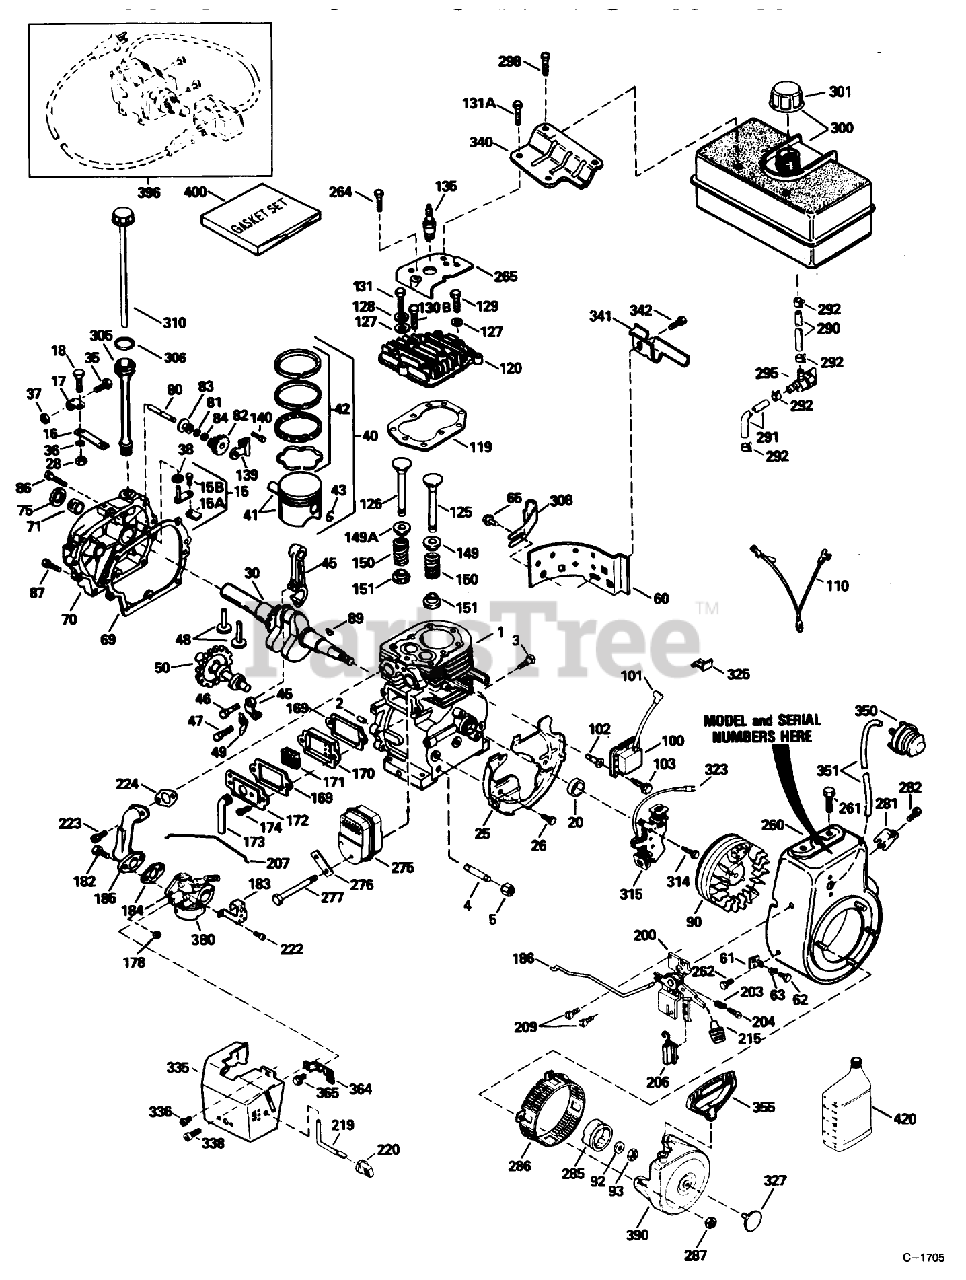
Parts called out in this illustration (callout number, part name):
1	Cylinder (Incl. ref. #2 20)
2	Pin-Dowel
3	Screw (1/4-20x1/2)
4	Nipple-Pipe
5	Cap-Pipe
15	Rod, Governor (Incl. Nos.62 63)
15A	Yoke-Governor
15B	Screw (6-40x5/16)
16	Lever-Governor
17	Clamp-Lever, Governor
18	Screw
18	Gasket-Carburetor To Intake Pipe
20	Seal-Oil
22	Gasket-Pipe, Intake
25	Baffle-Blower Housing
26	Screw (1/4-20x19/32)
28	Nut-Lock
30	Crankshaft
35	Screw
36	Washer-Lock
37	Nut-Lock
38	Ring-Retaining
40	Piston, Pin Ring Assy. Std.(Includes ref. #41, 42 43)
41	Piston Pin Assembly Standard (Includes ref. #43)
42	Ring Set (STD)
43	Retaining Ring-Piston Pin
45	Rod Assembly-Connecting (Incl. ref. #46, 47 49)
46	Bolt-Rod
47	Bolt-Rod
48	Lifter-Valve
49	Dipper-Oil
50	Camshaft (MCR)
60	Extension-Housing, Blower
61	Bracket
62	Screw (8-32 x 3/8)
63	Grommet
65	Screw
69	Cylinder Cover Gasket
70	Cover-Cylinder (Includes 71, 75, 80)
71	2025A77 WIZARD ROTA
75	Seal-Oil
80	Shaft-Governor
81	Washer-Flat
82	Gear Assy., Governor (Incl. Ref. #45)
83	Spool-Governor
84	Ring-Retaining
86	Screw (1/4-20x1-3/16)
87	Screw (1/4-20x1-11/16)
89	Key-Flywheel
90	Flywheel ASM
92	Washer-Belleville
93	Nut-Flywheel
100	Solid State ASM
101	Cover-Spark Plug
103	Screw
110	Ground Wire
120	Head-Cylinder
125	Valve, Exhaust (Standard)(Incl. No. 9)
126	Valve, Intake (Std.) (Incl. Ref. #58)
127	Washer-Flat
128	Washer-Belleville
129	Screw (5/16-18x1-25/32)
130	Screw
131	Screw (5/16-18 X 2)
131A	Screw
135	Spark Plug-Resistor (R J19 L M)
139	Bracket-Gear, Governor
140	Screw (10-24x1/2)
149	Cap-Spring, Valve
149A	51106 GILSON ROTARY
150	Spring-Valve
151	Keeper-Spring, Valve
170	Body-Breather
171	Element-Breather
172	Cover-Valve
173	Tube-Breather
174	Screw
178	Nut and Lock Washer (1/4-28)
182	Screw (1/4-28x1)
183	Bracket-Choke
185	Pipe-Intake
186	Link-Governor
200	Bracket-Control (Includes 19, 203, 204, 206)
203	Spring-Compression
204	Screw
206	Terminal
207	Link-Throttle
209	Screw (10-32 x 1/2)
215	Knob-Control
219	Rod-Choke
220	Knob-Control
222	Screw (10-32 x 1/2)
223	Screw (T-30, 5/16-18x1-3/32)
260	Housing-Blower
261	Screw (5/16-18x3/4)
262	Screw
265	Cover-Cylinder Head
275	Muffler
276	62513 SNWTHWR W/284
277	Screw
281	Screw
282	Screw (8-32 x 3/8)
285	Hub-Starter
286	Screen-Starter
287	Nut and Lock Washer (1/4-28)
290	Line-Fuel (8.62)
291	Line-Fuel
292	Clamp-Line, Fuel
295	Valve-Shut Off, Fuel
298	Screw (1/4-15x7/8)
300	Tank-Fuel (Includes 292, 301)
301	Cap-Fuel
305	Tube-Fill, Oil
306	O-Ring
308	Clip-Tube, Fill
310	Gauge Oil ASM
314	Screw (1/4-20 x 3/4)
316	Coil-Alternator, 18 Watt (Includes 323)
323	Terminal
325	Clip-Wire
327	Plug Starter
336	Screw (10-32x1/2)
338	Screw (10-32 x 3/8)
340	Bracket-Tank, Fuel
341	Bracket-Tank, Fuel (Black)
342	Screw (1/4-20x19/32)
350	Primer-Asm
351	Line-Primer
355	Handle-Starter, Mitten Grip
364	Bracket-Carburetor
365	Screw (8-32x27/64)
380	Screw-Hex Washer Hd.
390	Rewind Starter
400	Gasket Set
421	Oil-Engine (SAE 5W30)
